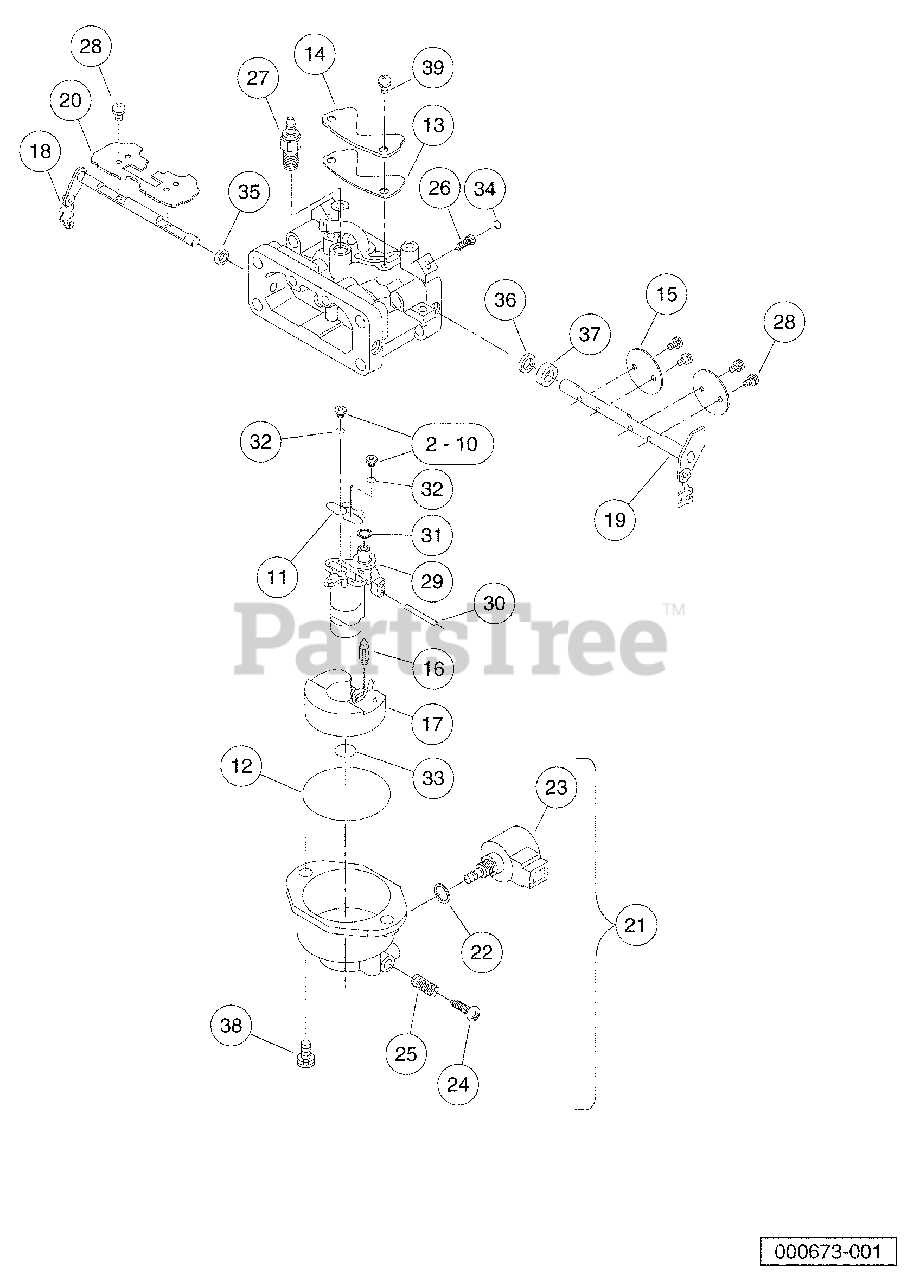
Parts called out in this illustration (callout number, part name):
1	Asm, Carburetor, Fh680d
2	Kit, Jet, 6600 Ft +, Fh680d
3	Jet, Push In #96, FH680D (6600 ft and higher (2000 m and higher))
4	Kit, Instructions Jet, Push In
5	Kit, Jet, 3300-6600 Ft, Fh680d
6	Jet, Push In #99, FH680D (3300-6600 ft (1000-2000 m))
7	Kit, Instructions Jet, Push In
8	Kit, Jet, 0-3300 Ft, Fh680d
9	Jet, Push In #102, FH680D (0-3300 ft (0-1000 m))
10	Kit, Instructions Jet, Push In
11	Gasket, Fh680d
12	Gasket, Carburetor, Dia. 52
13	Gasket, Cover, Fh680d
14	Cover, Slow Passage, Fh680d
15	Valve, Throttle, Fh680d
16	Valve, Float, Fh680d
17	Float, Carburetor, Fh680d
18	Shaft, Carburetor, Fh680d
19	Shaft, Carburetor, Throttle
20	Valve, Carburetor, Fh680d
21	Asm, Chamber, Float, Fh680d (includes items 22 through 25)
22	Gasket, Carburetor, Fh680d
23	Solenoid, Carburetor, Fh680d
24	Screw, Drain, Carburetor
25	Spring, Carburetor, Fh680d
26	Needle, Jet, Fh680d
27	Heater, Carburetor, Fh680d
28	Screw, Carburetor, M3 X 6
29	Spacer, Carburetor, Fh680d
30	Pin, Carburetor, Fh680d
31	O-ring, Carburetor, Dia. 6.5
32	O-ring, Carburetor, Fh680d
33	O-ring, Carburetor, Dia. 9
34	Plug, Expansion, Carburetor
35	Seal, Carburetor, Dia. 5.9
36	Seal, Carburetor, Fh680d
37	Collar, Carburetor, Fh680d
38	Screw, Carburetor, M5
39	Screw, Carburetor, M4
